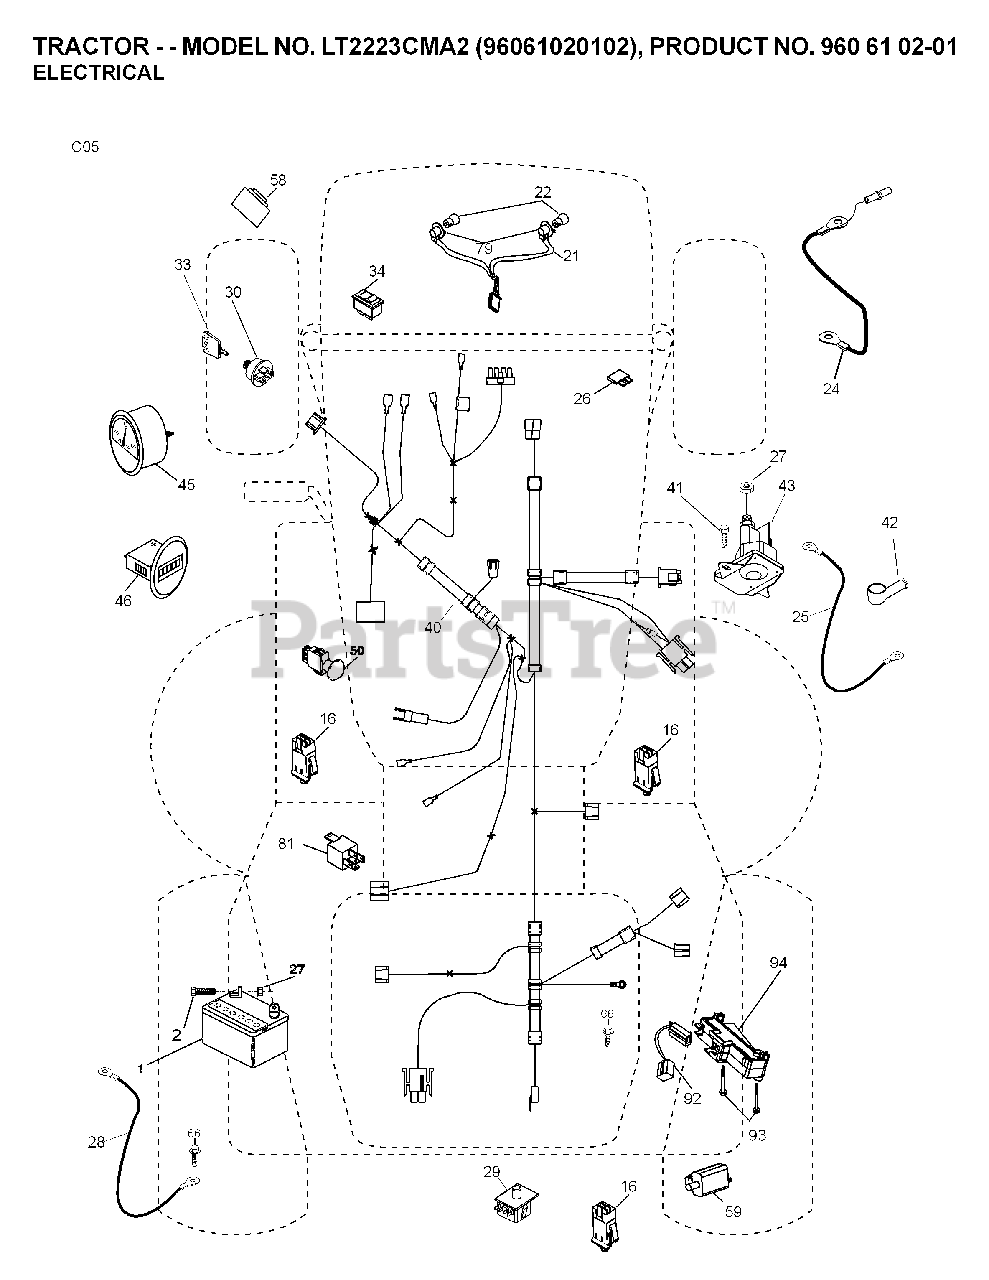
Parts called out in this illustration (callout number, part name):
1	REPL BY 532 12 38-99
16	SWITCH INTERLOOK PUSH-IN
21	HARNESS.W/LIGHT SOCKET
22	LIGHTBULB
24	BATTERY CABLE GT
25	CABLE BATTERY
26	FUSE 20AMP
27	NUT
28	CABLE GROUND
29	SWITCH.SEAT.DP W/RAMPS
30	SWITCH.IGN.DELTA.W.LGH.ROS
33	KEY.CHAIN.BLISTER.PACK.GEN.INT
34	SWITCH LT
42	TERMINAL COVER
43	SOLENOID.W/BRASS.PLUNG
46	HOURMETER SNAP-IN
50	PTO SWITCH
58	BUZZER
79	BULB HOLDER ASM.
81	RELAY.ASSY.T
92	HARNESS.PIGTAIL.CONSLE
93	SCREW.PLASTITE
94	MODULE.REVERSE.ROS
